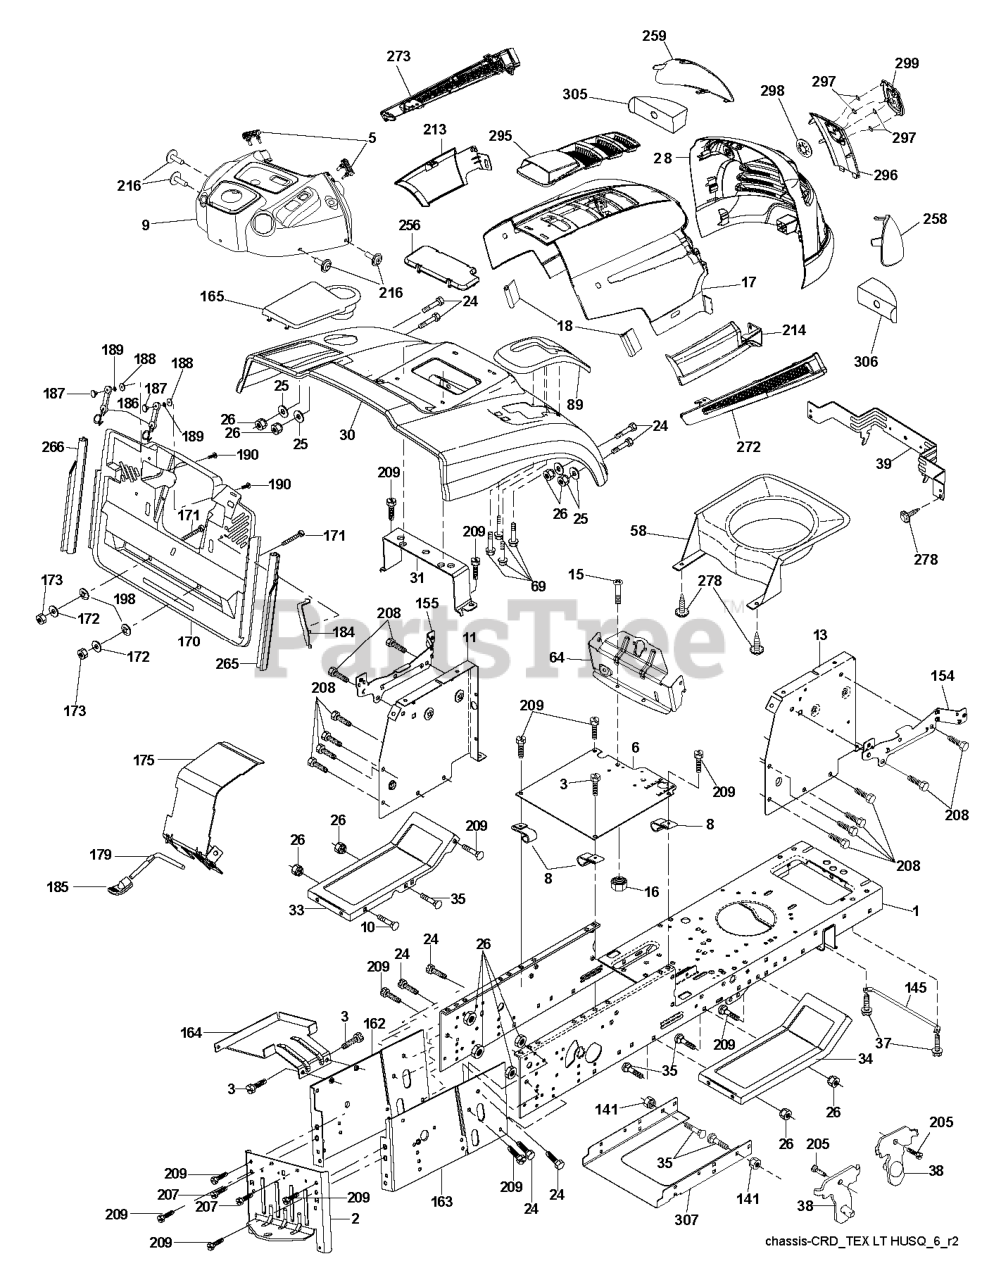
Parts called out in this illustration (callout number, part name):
2	DRAWBAR
3	SCREW 3/8-16X3/4
5	BUMPER DASH
6	PLATE
8	CLIP,INSULATOR
10	BOLT D
11	PANEL.DASH.LH.LTX
13	PANEL ASM, DASH RH
15	Screw, Machine, Truss Head 5/16-18 UNC x 3/4
16	NUT
17	HOOD.HUSQVARNA.LT.ORANGE
18	BUMPER.HOOD.TEX.HUSQVARNA
25	WASHER
26	NUT
28	GRILLE.SVC.HUSQVARNA.LT.GREY
30	CONSOLE.CRD.AUTO.GRY
31	BRACKET SUPPORT FENDER
33	FOOTREST PNT LH
34	FOOTREST PNT RH
37	Screw 5/16-18 x 1/2 Hex, Self Tapping 5/16-18 x 1/2
38	BRACKET ASM PIVOT MOWER REAR
39	BRACKET PIVOT
69	SCREW.HI-LO.CONSOLE
89	CONSOLE.CRD.AUTO.GREY.2005
141	NUT LOCK FLG 3/8-16 UNC
145	ROD.PIVOT.HOOD
162	BRACKET
163	BRACKET EXTEN CHASSIS RH CRD
165	RP.COVER.BATTERY.CRD.GREY
172	WASHER
175	DOOR TRAP
179	ROD PIVOT FBI
184	BRACKET.ACTUATOR.BAGGER.SRD
186	LATCH ASSY
187	WELDNUT
189	LOCKWASHER #10
190	SCREW
207	SCREW, 5/16-18 X 1/2
208	SCREW 3/8-16X1/2
209	SCREW, 3/8-16X3/4
213	SKIRT SIDE LH
214	SKIRT SIDE RH
216	SCREW HEXWSHR 1/4-20X3/4
256	COVER FENDER CRD
258	LENS.HUSQVARNA LT.RH
259	LENS.HUSQVARNA LT.LH
265	SEALING
266	SEALING
272	VENT SIDE HOOD LH
273	VENT SIDE HOOD RH
278	SCREW.#10 X 0.750.BOS
295	VENT TOP HOOD
296	TRIM
297	CLIP.RETAINER.TINNER.
298	NUT PUSH M
299	RP LOGO
305	INSERT REFLECTIVE
306	INSERT.REFLECTIVE.RH.
